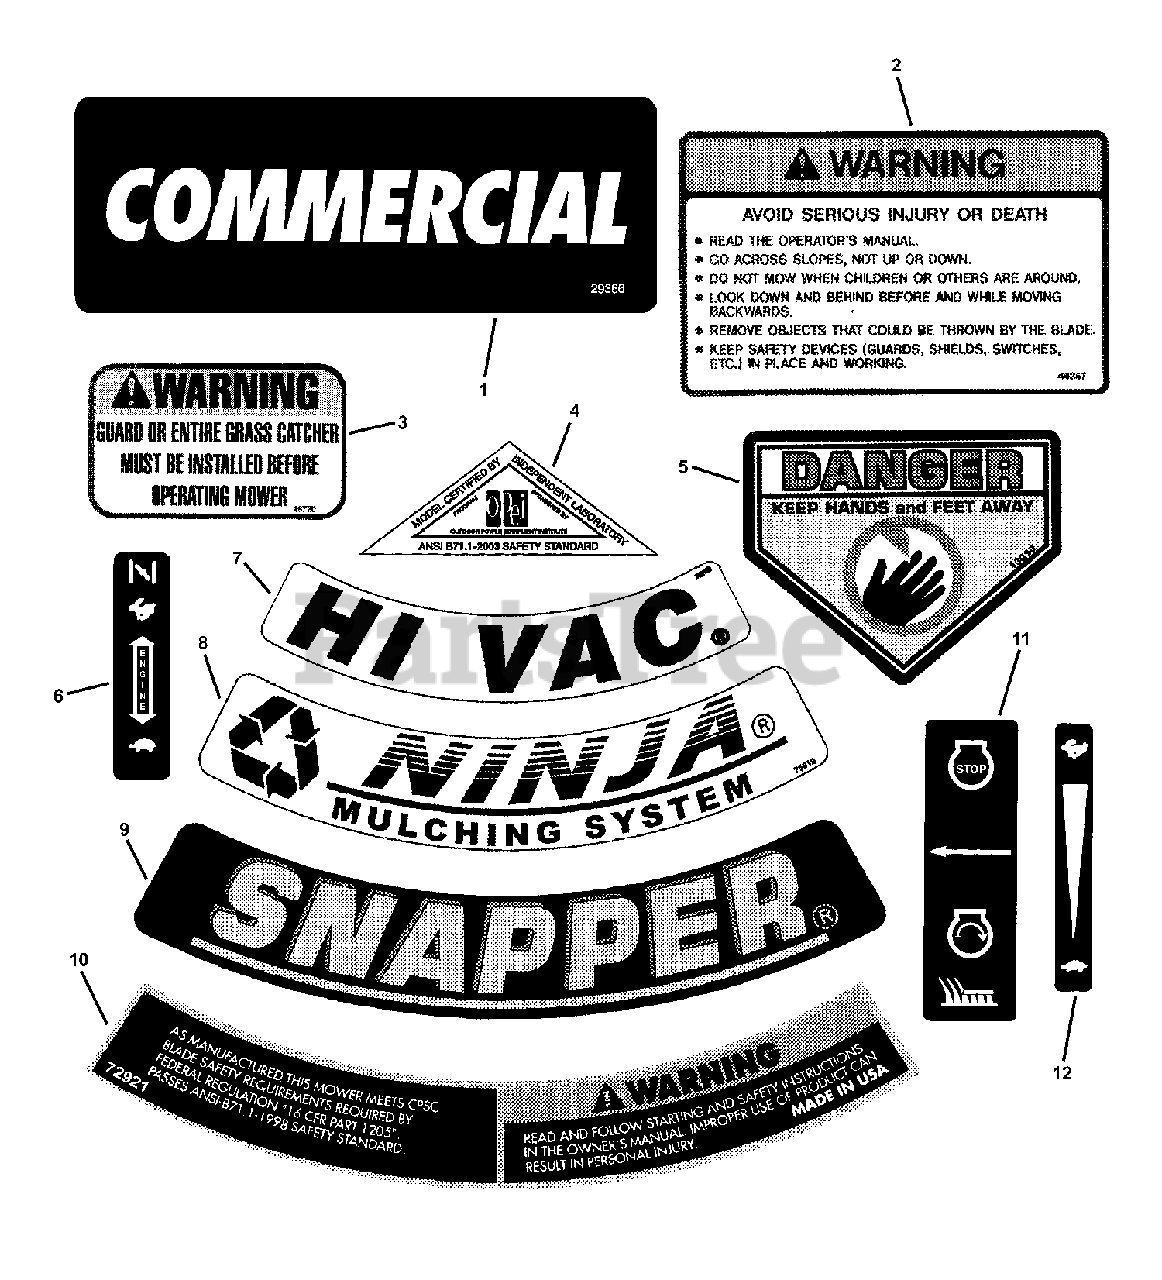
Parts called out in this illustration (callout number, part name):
1	DECAL, Commercial, WBM
2	DECAL, Warning
3	DECAL, Chute/Deflector
4	DECAL, OPEI Walk/Ride
5	DECAL, Danger, Cut Finger
6	DECAL, Throttle Control, KWV
7	DECAL, Hi Vac
8	DECAL, Ninja
9	DECAL, Snapper
10	DECAL, Warning (Deck)
11	DECAL, OPC Bail (International Symbol)
12	DECAL, Speed Shift
